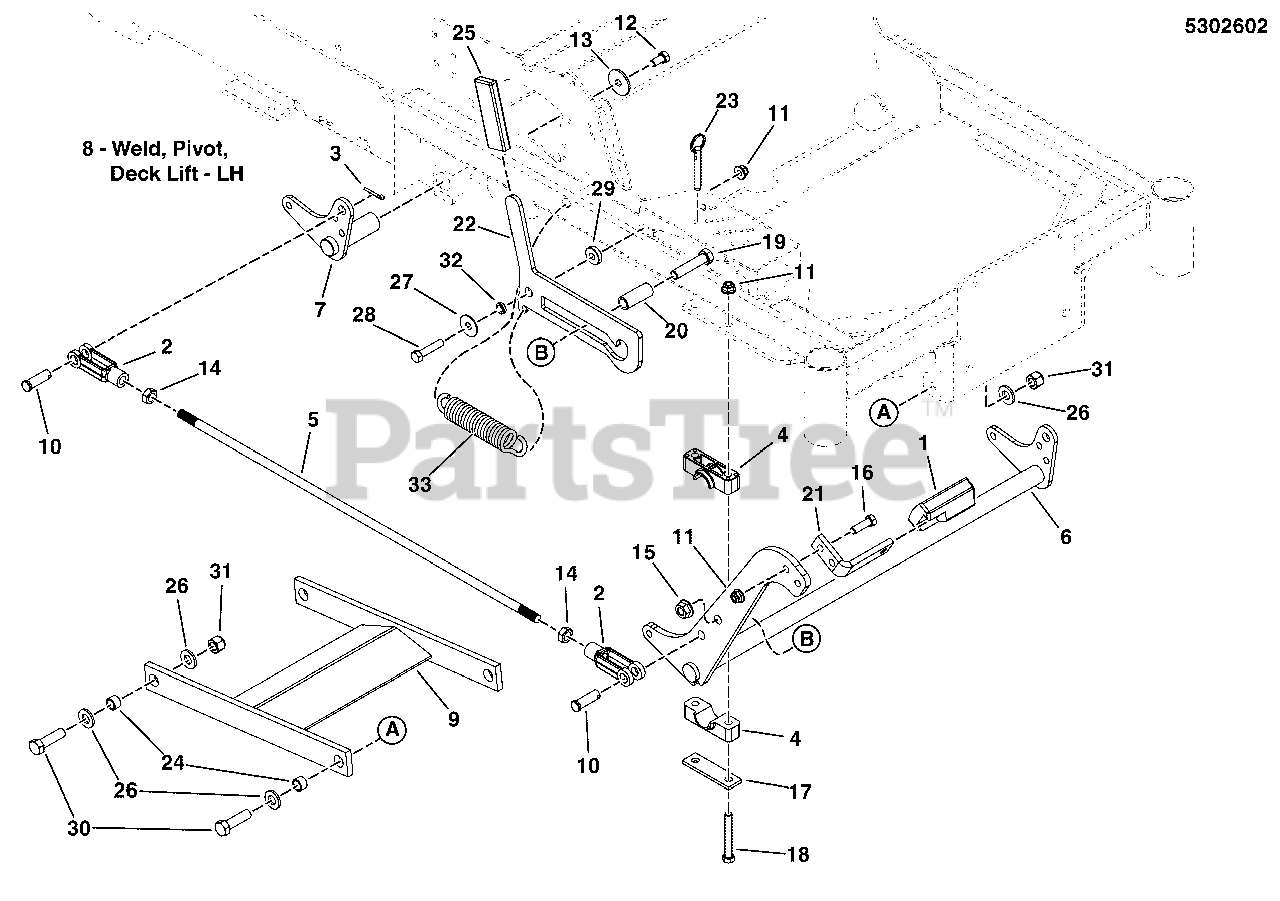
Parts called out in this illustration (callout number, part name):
1	PEDAL, Rubber
2	CLEVIS, 1/2-20, STEEL, CLEAR ZINC
3	PIN, HAIR, .0915 X 1-7/8
4	PIVOT BLOCK, PLASTIC
5	ROD, DECK LIFT, SNAPPER PRO
6	WELD, FRONT DECK PIVOT - RED
7	WELD, PIVOT, DECK LIFT, RH - BLK
9	WELD, PULLER BAR - BLK
10	PIN, CLEVIS, 1/2 X 1-1/2, PLATED
11	NUT, 3/8 - 16 HEX NYLOCK FLANGE
12	BOLT, 3/8-16 X 3/4, PLT W/PATCH
13	WASHER, .390 X 1.50 X .109, YZ
14	NUT, 1/2-20 Hex Jam
15	NUT, 1/2-13 HEX NYLOCK FLANGE
16	BOLT, 3/8-16 X 1-1/4" GD5 CZ
17	PLATE, PIVOT BLOCK SUPPORT - BLK
18	BOLT, 3/8-16 X 2-3/4" GD5 CZ
19	BOLT, 1/2-13 X 4-1/4 GD5 YZ
20	SPACER, .53 X .73 X 3.38, CZ
21	PEDAL, FOOT - RED
22	PLATE, DECK TRANSPORT LEVER - RED
23	HITCH PIN, 3/8 X 2-1/2, COTTERLESS, CZ
24	INSERT, Bearing
25	GRIP, FOAM, 1/4 X 1 X 4.1
26	WASHER, 1/2" GD9 YZ
27	WASHER, 3/8" Fender
28	BOLT, 3/8-16 X 1-3/4" GD5 CZ
29	SPACER, .39 X 1.00 X .25, PM, CZ
30	BOLT, 1/2-20 X 1-3/4" GD8 CZ
31	NUT, Hex, Nylon Lock, 1/2-20
32	SPACER, .38 X .50 X .27, CZ
33	SPRING, EXTENTION, .50 OD X 4.12 FL
